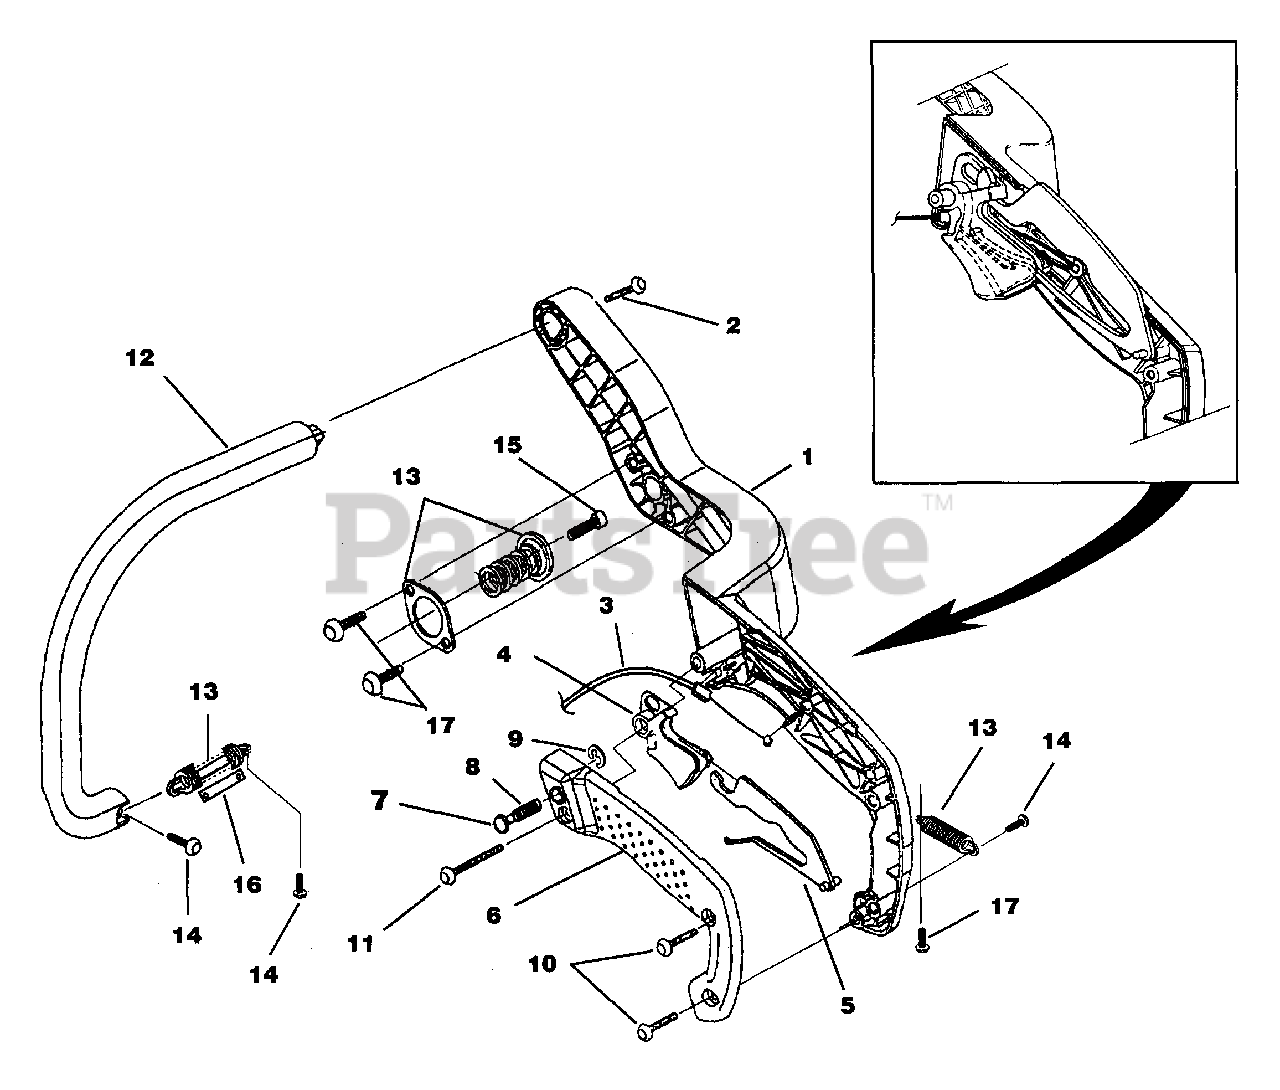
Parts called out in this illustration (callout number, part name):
1	Rear Handle Kit
2	Screw-Pan Hd. (12-14 x 1 1/2")
3	Throttle Cable
4	Trigger, Throttle
5	Throttle Lock Out
6	Handle Cover Kit
7	Throttle Lock Pin
8	Spring, Compression
9	Ring, Retainer
10	Screw, Thread Form (10-14 x 3/4")
11	Screw, Thread Form (10-14 x 1 3/8")
12	Front Handle Kit
13	Isolator Kit
14	Screw, Truss Hd. (10-14 x 5/8")
15	Screw, Truss Hd. (10-24 x 5/8")
16	Limiter, Isolator
17	Screw, Thread Form (10-14 x 1/2")
